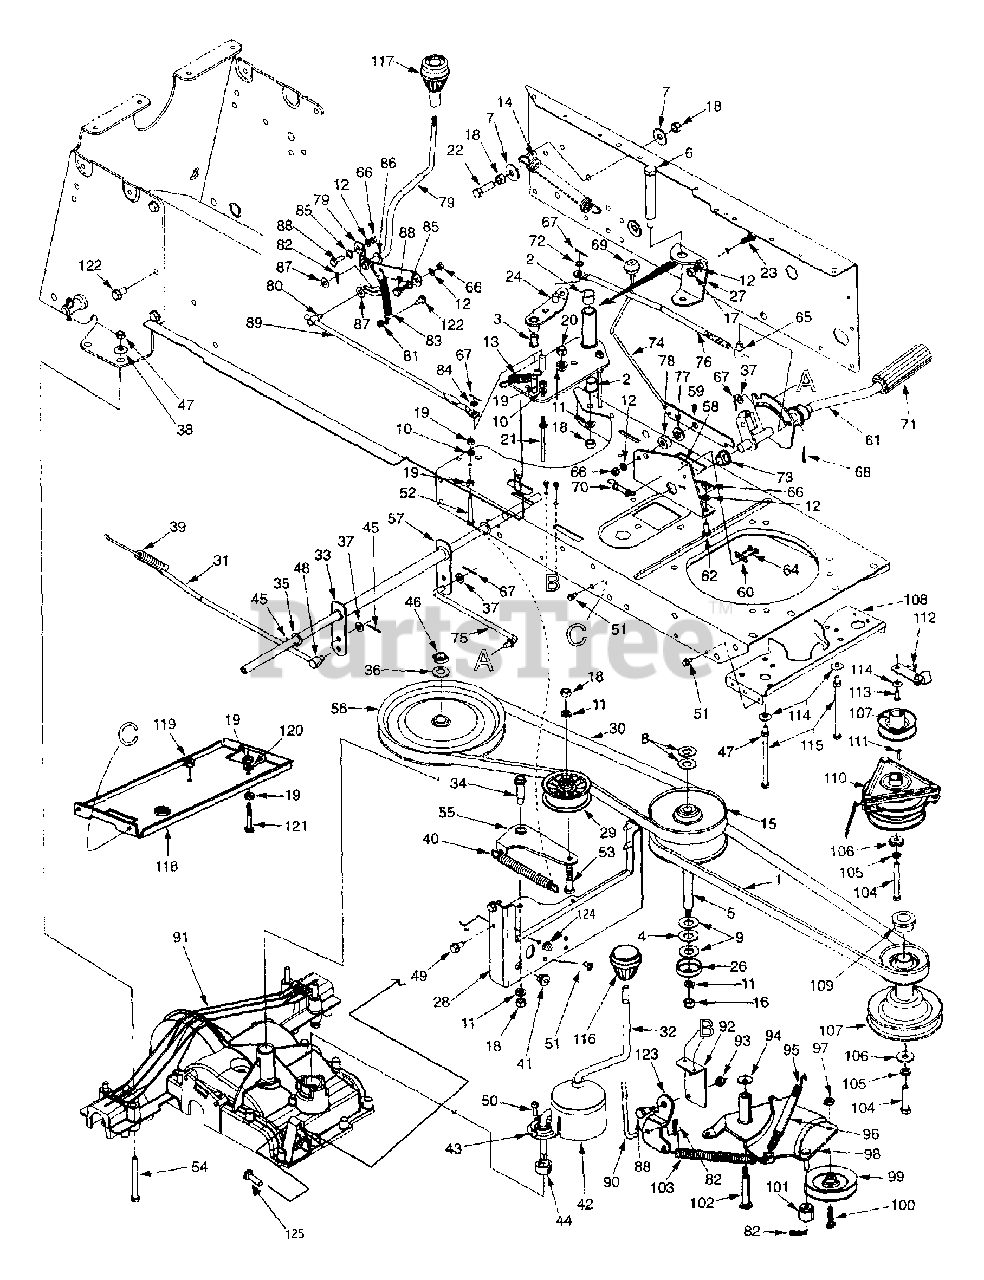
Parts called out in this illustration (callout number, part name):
1	"V" - Belt
2	Flange Brg.
3	Flange Nyliner Brg.
4	Thrust Brg.
5	Shaft
6	Shld. Bolt 3/8-24 Thd.
7	Bell-Wash. .396" I.D. x 1.14" O.D.
8	Fl-Wash. .56" I.D. x 1.12" O.D.
9	Fl-Wash. .5" I.D. x 1" O.D.
10	L-Wash. 1/4" I.D.
11	L-Wash. 3/8" I.D.
12	L-Wash. 5/16" I.D.
13	Ext. Spring 2.54" Lg.
14	Ext. Spring 6.96" Lg.
15	Variable Speed Pulley
16	Hex L-Nut 3/8-24 Thd.
17	Hex Nut 5/16-24 Thd. (Gr. 5)
18	Hex Nut 3/8-16 Thd. (Gr. 5)
19	Hex Nut 1/4-20 Thd. (Gr. 5)
20	Hex Nut 3/8-24 Thd.
21	Belt Keeper
22	Hex Bolt 3/8-16 x 1.25" Lg.
23	Hex Bolt 5/16-24 x .75" Lg. (Gr. 5)
27	Support Brkt.
30	"V" - Belt
31	Brake Rod
32	Shift Lever
33	Flange Nyliner Brg.
34	Shld. Bolt 3/8-16 Thd.
35	Fl-Wash. .5" I.D. x .875" O.D.
36	Bell-Wash. .567" I.D. x 1.125" O.D.
37	Fl-Wash. 5/16" I.D.
38	Bell-Wash. .345" I.D. x .88" O.D.
39	Ext. Spring 7.3" Lg.
40	Ext. Spring 6.12" Lg.
41	Plastic Bushing
42	Boot Shifter
43	Shifter Snout
44	Shifter Insert
45	Cotter Pin 1" Lg.
46	Hex Jam Nut 9/16-18 Thd.
47	Hex Nut 5/16-18 Thd. (Gr. 5)
48	Ferrule
49	Hex Wash. AB-Tap Scr. 5/16-18 Thd.
50	Hex Wash. TT-Tap. Scr. 1/4-20 x .75" Lg.
51	Hex Wash. Hd. TT-Tap Scr. 1/4-20 x .5" Lg
52	Hex Bolt 1/4-20 x 2" Lg. (Gr. 5)
53	Hex Bolt 3/8-16 x 1.75" Lg. (Gr. 5)
54	Hex Bolt 5/16-18 x 3" Lg. (Gr. 5)
56	Trans. Pulley
64	Hex Hd. Tap Scr. #10-16 x .75" Lg.
65	Ferrule
66	Hex Nut 5/16-18 Thd.
67	Cotter Pin 1" Lg.
68	Cotter Pin 1/8" Dia. x 1" Lg.
69	Ball Knob
70	Ext. Spring 2.51" Lg.
71	Foot Pad
72	Fl-Wash. 3/8" I.D. x .62" O.D.
73	Hex Flange Bearing
74	Pedal Lock Rod
75	Brake Link Rod
76	Speed Control Link
77	Shld. Spacer
78	Spacer .34" I.D. x .87" O.D.
79	Speed Selector Lever Ass'y.
80	Ferrule
81	Hex L-Nut 5/16-18 Thd.
82	Hairpin Clip
83	Ext. Spring 3.97" Lg.
84	Fl-Wash. 3/8" I.D. x .62" O.D.
85	Spr. Wash. 7/16" I.D.
86	Fl-Wash. .531" I.D. x .93" O.D.
87	Fl-Wash. 3/8" I.D. x .87" O.D.
88	Shld. Bolt .437" x .286"
89	Speed Control Link Rod
90	Deck Control Rod
91	Transmission Complete
92	Parking Brake Mtg. Brkt.
93	Hex L-Nut 5/16-18 Thd.
94	Bell-Wash. .38" I.D. x .88" O.D.
95	Extension Spring 6.37" Lg.
96	Conduit 4" Lg.
97	Hex Cent. L-Nut 3/8-24 Thd.
98	Idler Brkt. Deck Ass'y.
99	"V" - Belt Idler
100	Hex Bolt 3/8-24 x 1.5" Lg.
101	Spacer
102	Shld. Bolt .498" Dia. x 2.05"
103	Extension Spring 6.12" Lg.
104	Hex Bolt 7/16-20 x 2.75" Lg.
105	L-Wash. 7/16" I.D.
106	Fl-Wash. .44" I.D. x 1.25" Lg.
107	Engine Pulley
110	Electric PTO
111	Sq. Key 1/4" x 1" Lg.
114	Bell-Wash. .345" I.D. x .88" O.D.
115	Hex Bolt 5/16-18 x 5.25" Lg.
116	Knob
117	Shift Knob
119	Hex Cent. L-Nut 3/8-16 Thd.
120	L-Wash. 1/4" I.D.
121	Hex Bolt 1/4-20 x 2" Lg.
122	Hex AB-Tap Scr. 5/16 x .75" Lg.
123	Deck Control Pivot Brkt.
124	Hex L-Nut 5/16-18 Thd.
125	Hex Bolt 5/16-18 x 1.375" Lg.
